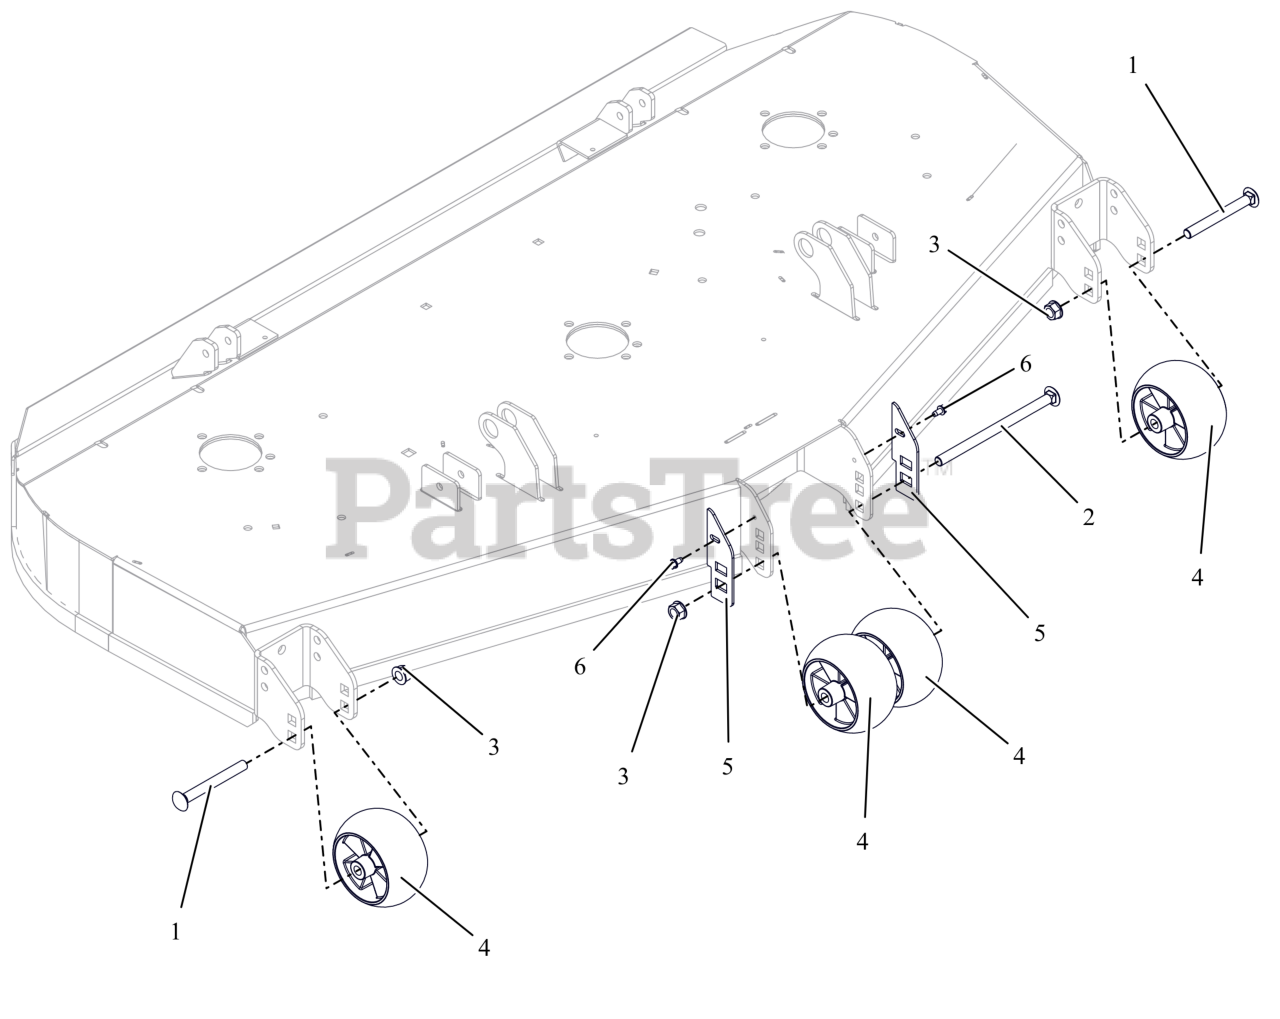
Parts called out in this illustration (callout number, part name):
1	BLT-RHNS .50-13X4.50 G5 ZCC NS
2	BLT-RHSN .50-13X8.00 G5 ZCC NS
3	NUT-LK-CTR-FLG .500-13 GG ZCC
4	WHEEL, ANTI SCALP - 5X3 CTR W/RIBS
5	PLATE, ANTI SCALP WHEEL 60" (ORANGE)
6	SCR-TAP .25-20X.50 HWH ZCC
